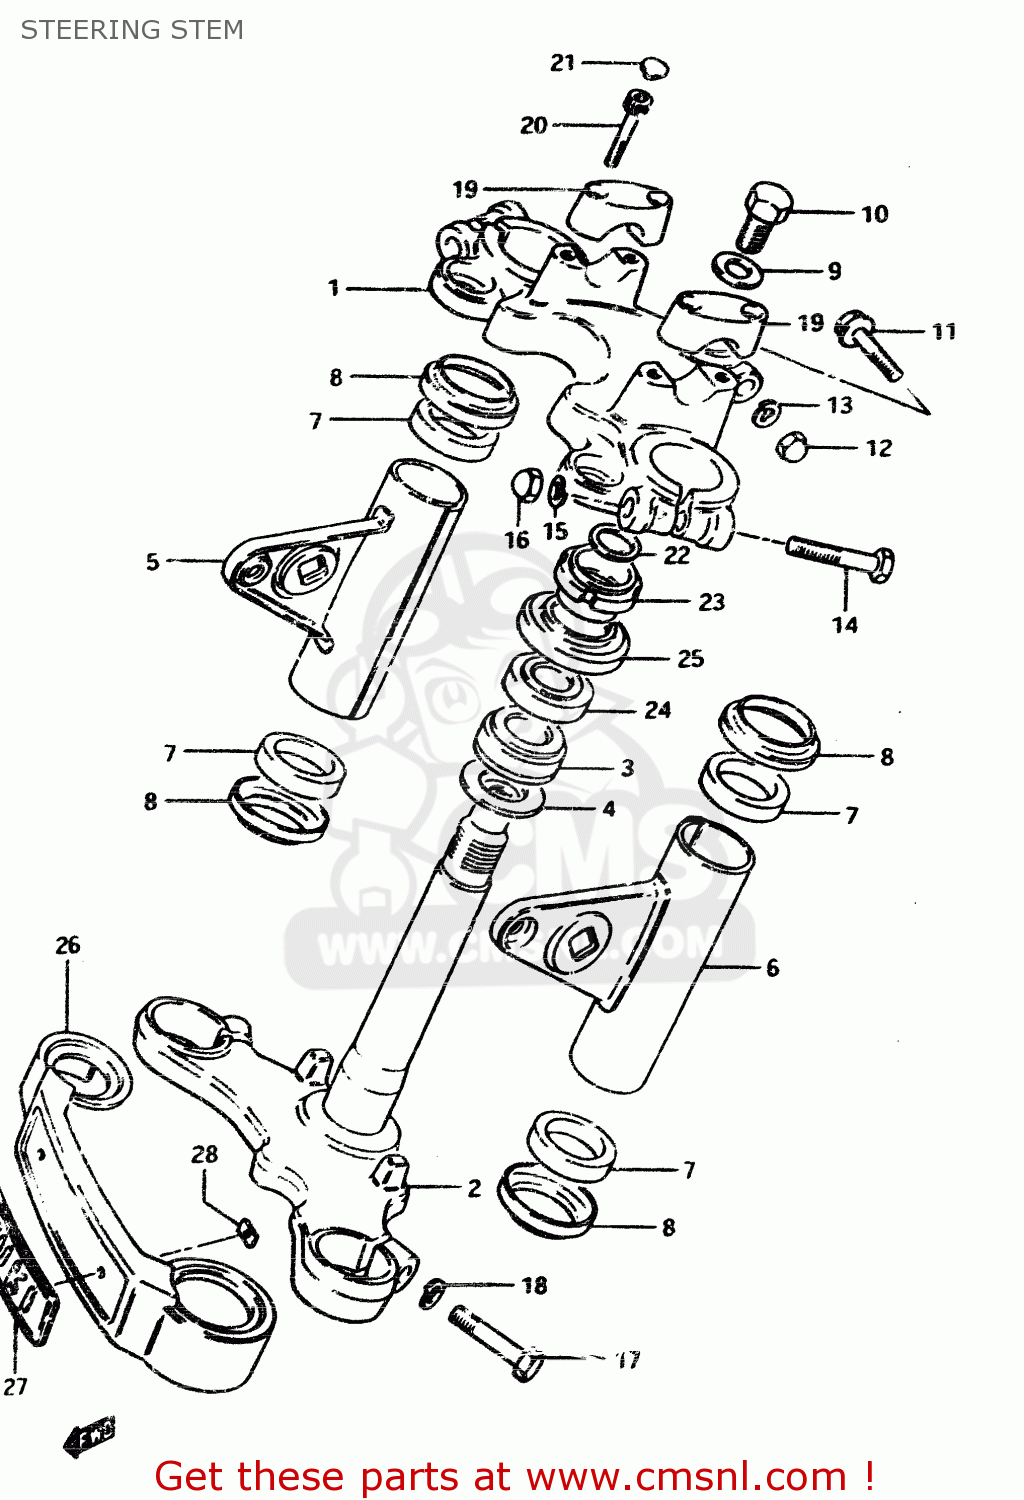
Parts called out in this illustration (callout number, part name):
1	HEAD,STEERING STEM
2	STEM,STEERING
3	BEARING
4	WASHER,THRUST
5	BRACKET,HEADLAMP,RIGHT
6	BRACKET,HEADLAMP,LEFT
7	CUSHION,HEADLAMP BRACKET
8	CAP,HEADLAMP BRACKET
9	WASHER (12.5X26X1.6)
10	BOLT 12X20
11	BOLT 8X50
12	NUT,M8X1.25X12
13	LOCK WASHER
14	BOLT 10X55
15	LOCK WASHER
16	NUT
17	BOLT 10X40
18	LOCK WASHER
19	HOLDER,HANDLEBAR(BLACK)
20	BOLT
21	CAP(OD:14.5)
22	WASHER(18.5X24X1)
23	NUT,STEERING STEM
24	TAPER,ROLLER BEARING
25	DUST SEAL,STEERING UPR
26	COVER,FRONT FORK
27	EMBLEM,FR FORK COVER
28	NUT
